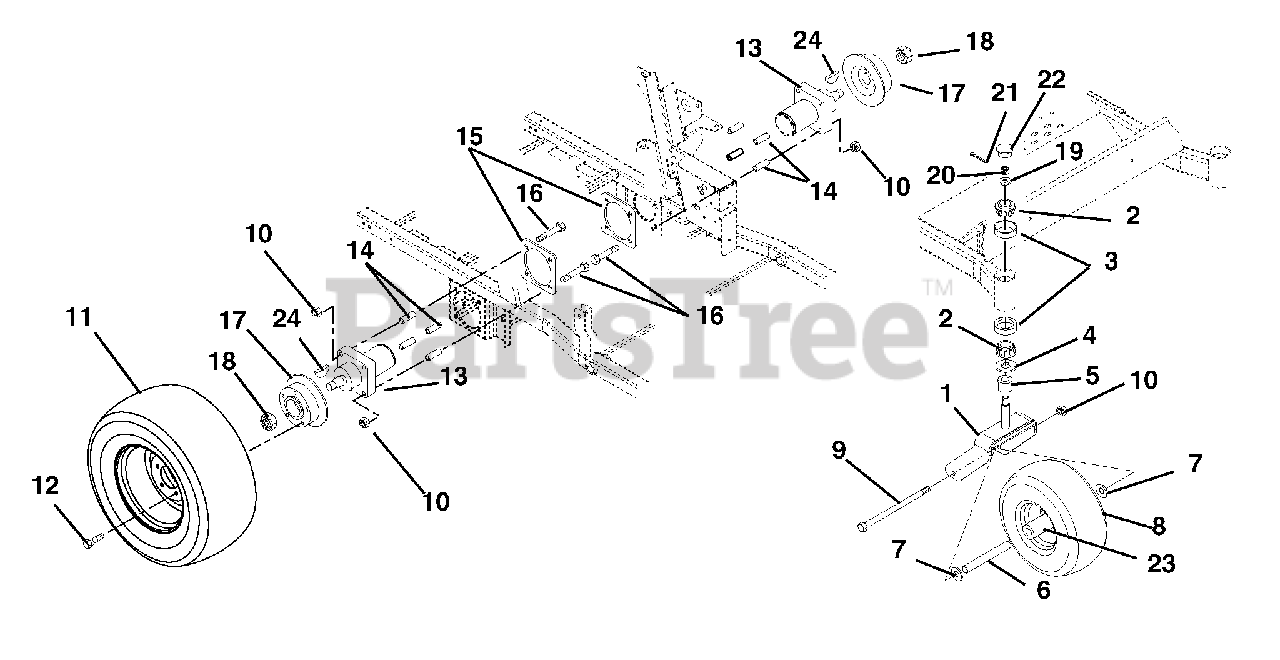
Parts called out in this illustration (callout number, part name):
1	Fork
2	Bearing, Cone with Grease
3	Bearing, Cup 1.980 x .420
4	Bearing Seal 1.5 x 2 x .18
5	Spacer, PM, 1.03 I.D. x 1.5 O.D. x .375
6	Spacer, Wheel
7	Washer, Flat Steel .515 x 1.625 x .25
8	Wheel/Tire Assembly
8	Tire, 15 x 6-6
9	Bolt, Hex .50-13 x 9.00 Grade 5
10	Nut, Locking Top Flange .50-13
11	Wheel, Tire 23 x 10.50 - 12 Multi-Trac (043, 044, 054, 311)
11	Wheel, Tire Assembly 23 x 10.50-12 (051, 054, 055)
11	Tire 23 x 10.50 (043, 044, 051, 054, 055, 311)
11	Wheel, Tire Assembly 23 x 9 50-12 (042, 310)
11	Tire, 23 x 9.50-12 Multitrac (042, 310)
12	Bolt, Lug Grade 8; .50-20 Unf x .75 Long 60 Degree
13	Hydraulic Wheel Motor
14	Bushing, Sleeve .513 x .748 x 2.13
15	Plate, Motor Support
16	Bolt, Hex .50-13 x 5.00 Grade 5
17	Hub and Disc
18	Nut, Lock Jam Patch
19	Washer, Flat Steel .755 x 1.375 x .062
20	Nut, Slotted .75-16
21	Pin, Cotter .16 x 1.00
22	Cap, Dust
23	Bearing, 25MM I.D. x 52MM OD x 15MM
24	Key, Woodruff .31 x 1.00
